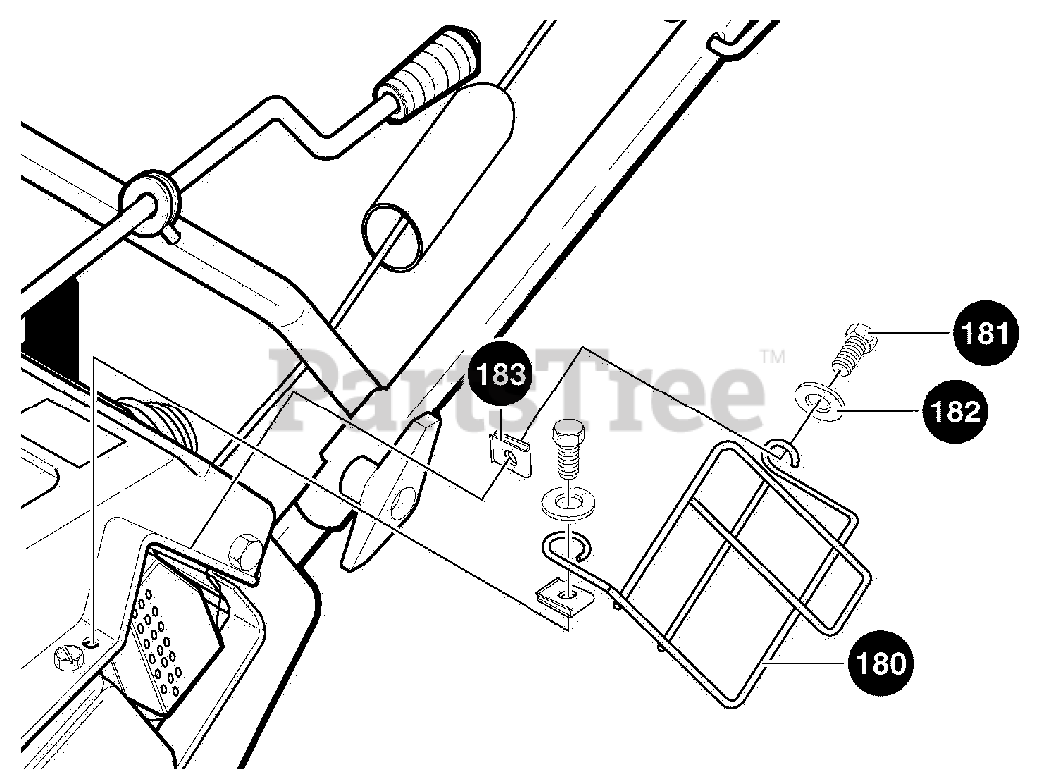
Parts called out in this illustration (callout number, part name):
180	GUARD, MUFFLER
181	SCREW
182	WASHER, FLAT
